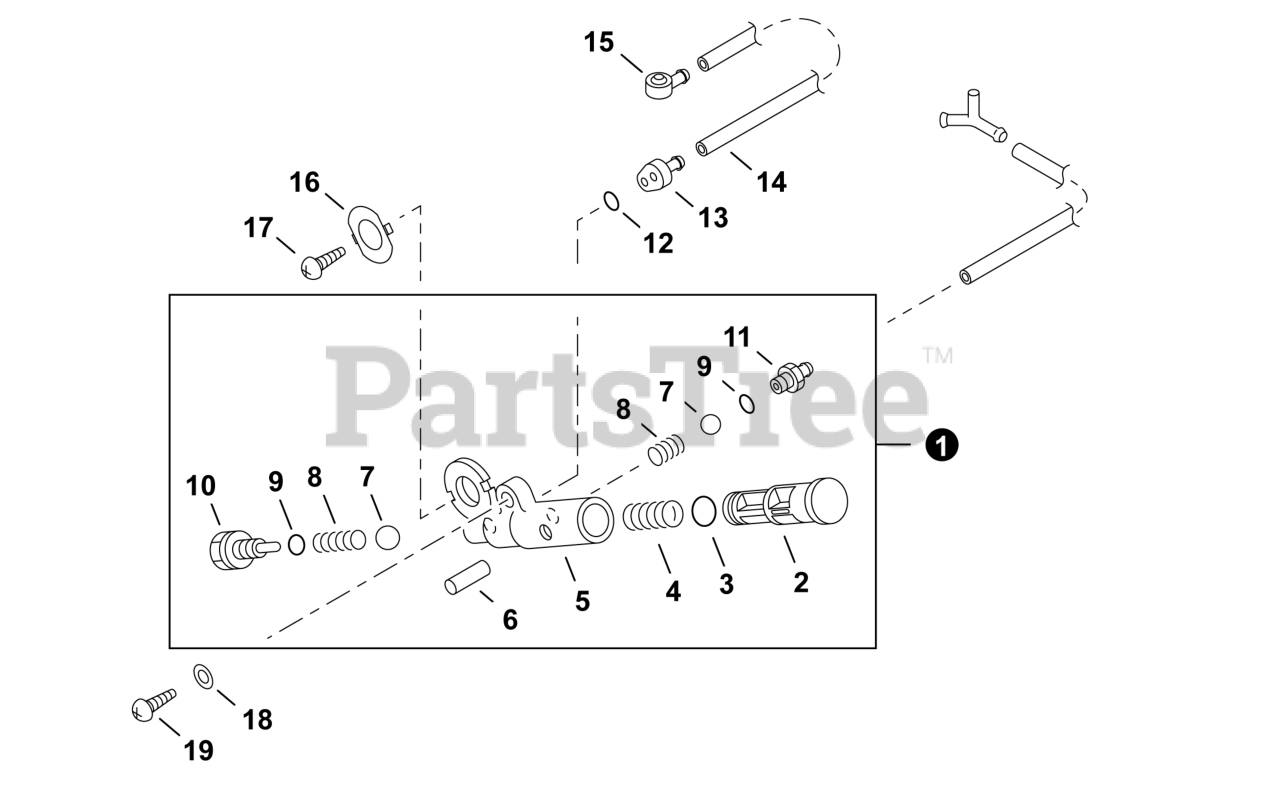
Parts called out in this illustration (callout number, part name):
1	OIL PUMP ASSY - ORANGE
2	PISTON, OIL PUMP - ORANGE
3	O-RING 7 MM
5	BODY, OIL PUMP
6	PIN, SPRING 2×16
7	VALVE, BALL
8	SPRING, COMPRESSION
10	ADAPTOR, OIL PUMP
11	CONNECTOR, PIPE
12	O-RING 3
13	CONNECTOR, PIPE
14	PIPE 3×6×125 BLACK
15	CONNECTOR, PIPE
16	BRACKET, OIL PUMP
17	SCREW 4×10
18	WASHER 5.5×12×0.8
19	SCREW 5×20
